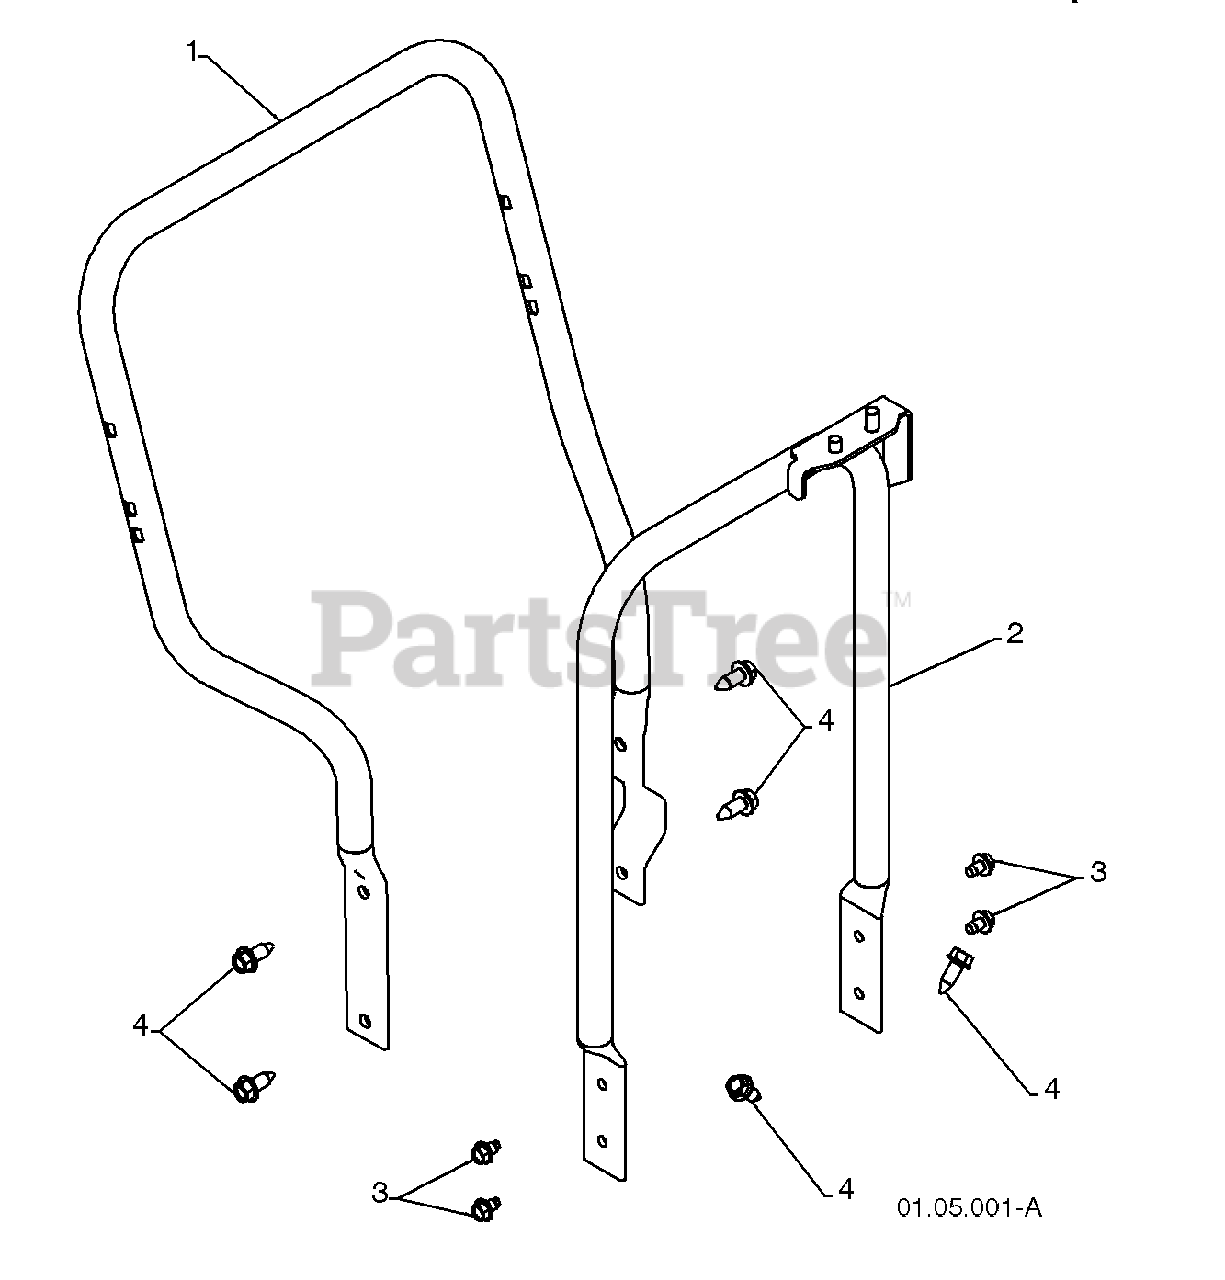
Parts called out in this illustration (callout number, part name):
1	LOWER TUBE
2	PIVOT SUPPORT
3	BOLT 5/16-18 X .500
4	SCREW 3/8-16 X 1.00
